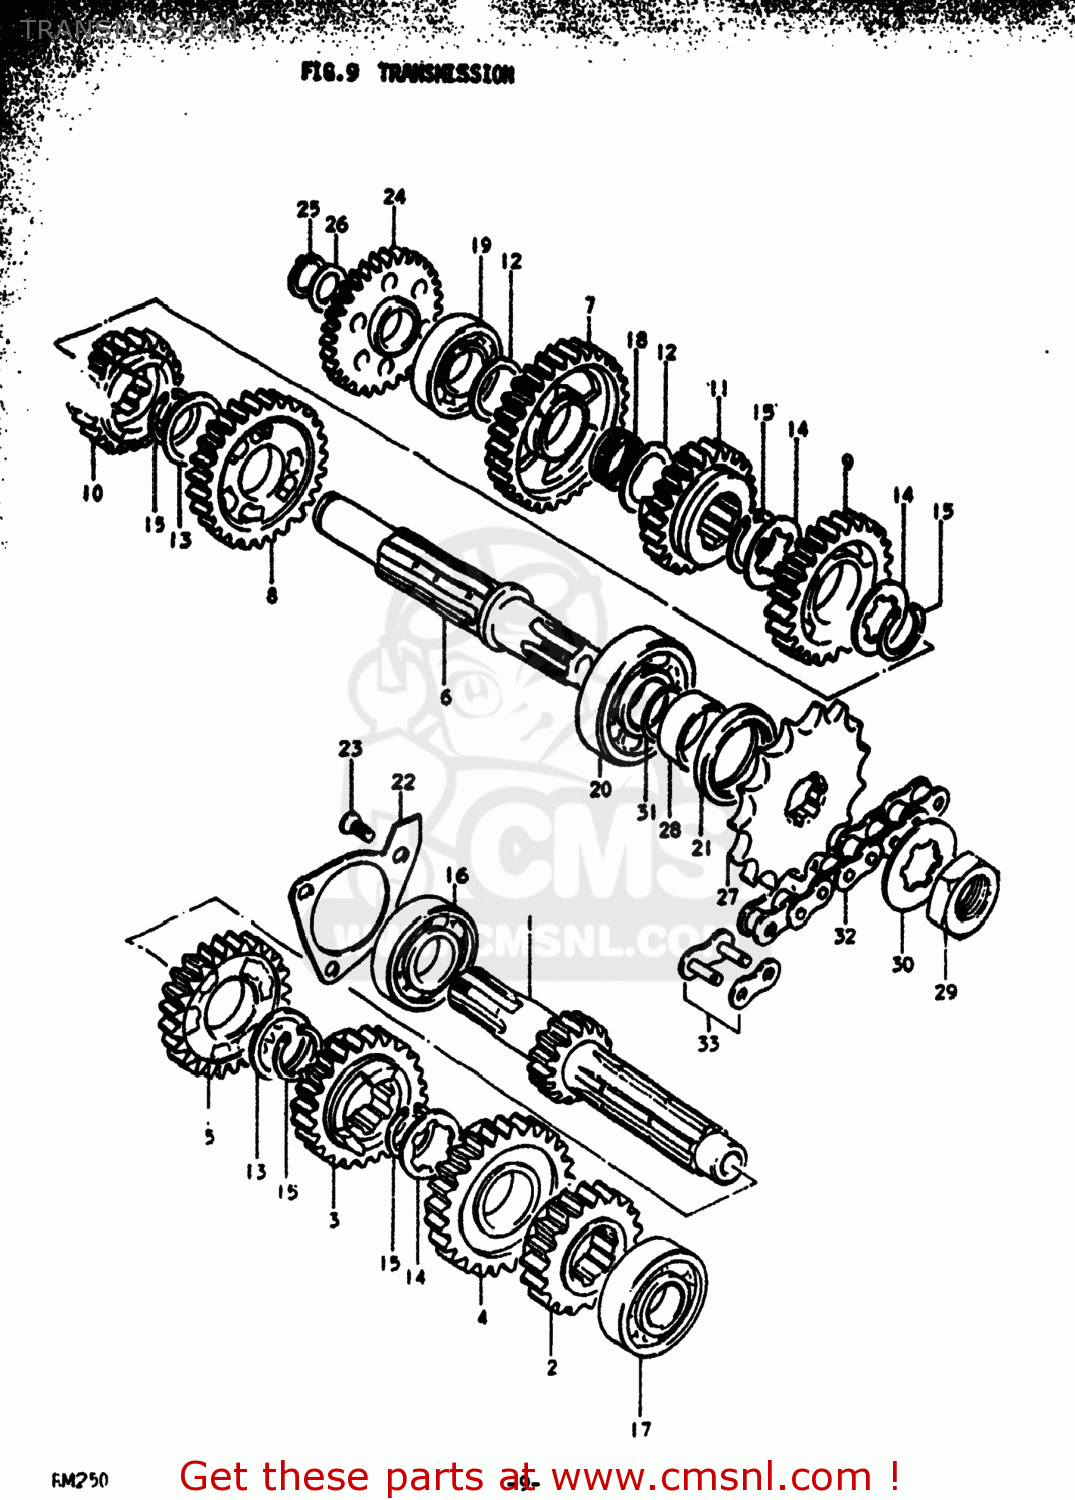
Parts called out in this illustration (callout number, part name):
1	SHAFT,COUNTER
2	GEAR,SECOND DRIVE
3	GEAR,THIRD DRIVE
4	GEAR,FOURTH DRIVE
5	GEAR,FIFTH DRIVE
6	SHAFT,DRIVE
7	GEAR,FIRST DRIVEN
8	GEAR,SECOND DRIVEN
9	GEAR,THIRD DRIVEN
10	GEAR,FOURTH DRIVEN
11	GEAR,FIFTH DRIVEN
12	WASHER
13	SHIM(22X28X0.5)
14	WASHER,LOCK
15	CIRCLIP
16	BEARING
17	BEARING
18	BEARING(17X21X9.8)
19	BEARING
20	BEARING
21	SEAL,OIL(32X42X6)
22	PLATE,COUNTERSHAFT BEARING
23	SCREW
24	GEAR,KICK STARTER IDLE
25	CIRCLIP
26	WASHER
27	SPROCKET,ENGINE
28	SPACER(22X32X11.5)
29	NUT
30	WASHER,LOCK
31	O RING(D:1.7,ID:22)
32	CHAIN ASSEMBLY,DRIVE
33	JOINT ASSEMBLY,CHAIN
